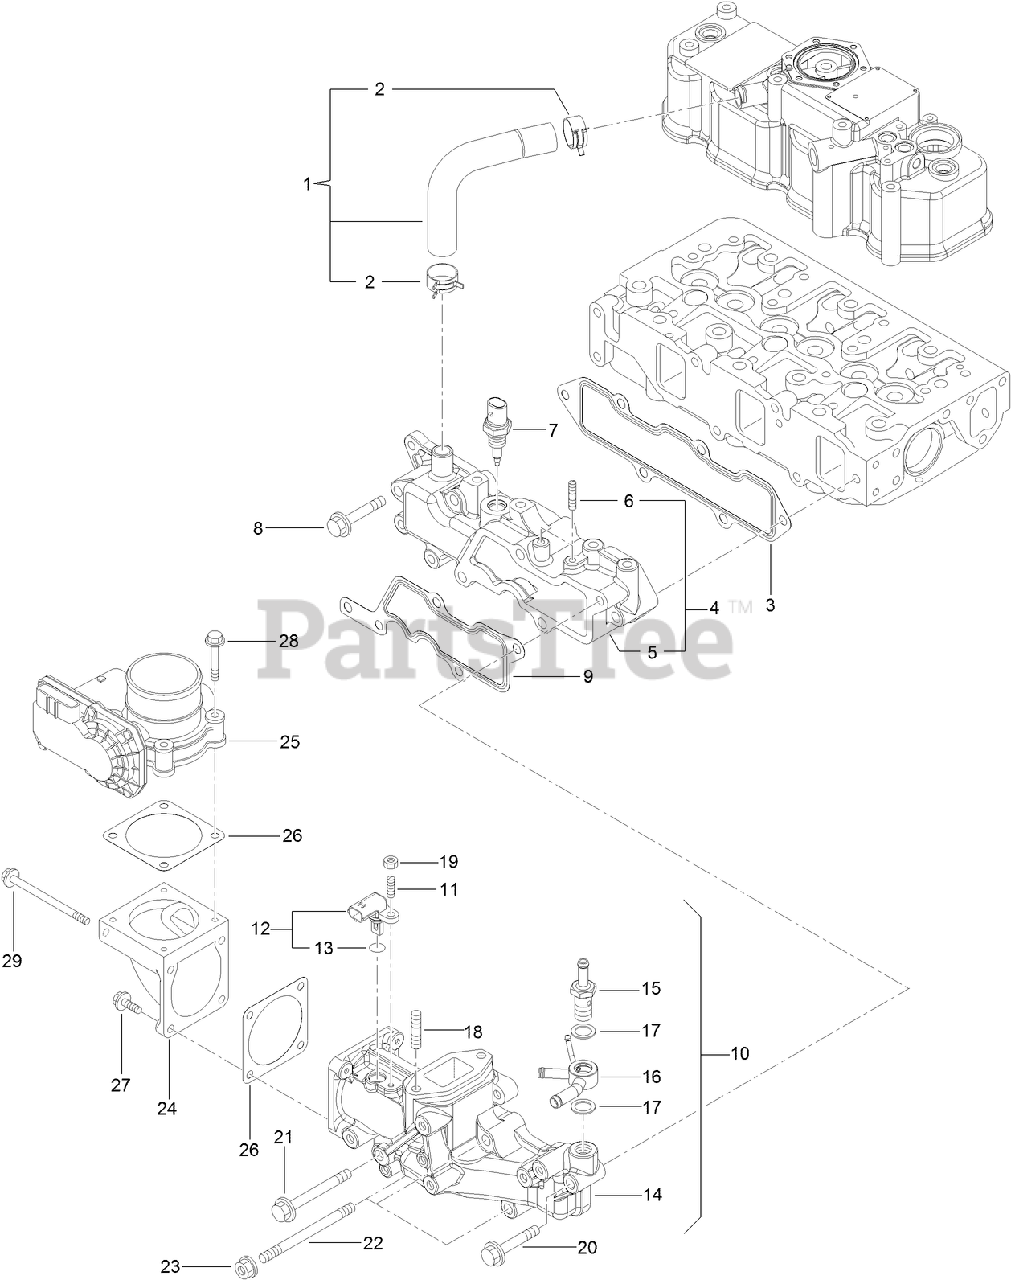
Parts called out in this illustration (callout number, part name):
2	CLIP-HOSE
3	GASKET-MANIFOLD, INTAKE
4	INTAKE MANIFOLD ASM
5	MANIFOLD-INTAKE
7	SENSOR-TEMP, AIR
9	GASKET-COLLECTOR
10	INTAKE COLLECTOR ASM
12	SENSOR-TEMP, AIR
13	O-RING
14	COLLECTOR-INTAKE
15	JOINT-HOSE
16	JOINT-HOSE
17	WASHER-SEAL
24	BEND-INLET
25	BODY-THROTTLE
26	GASKET-THROTTLE
